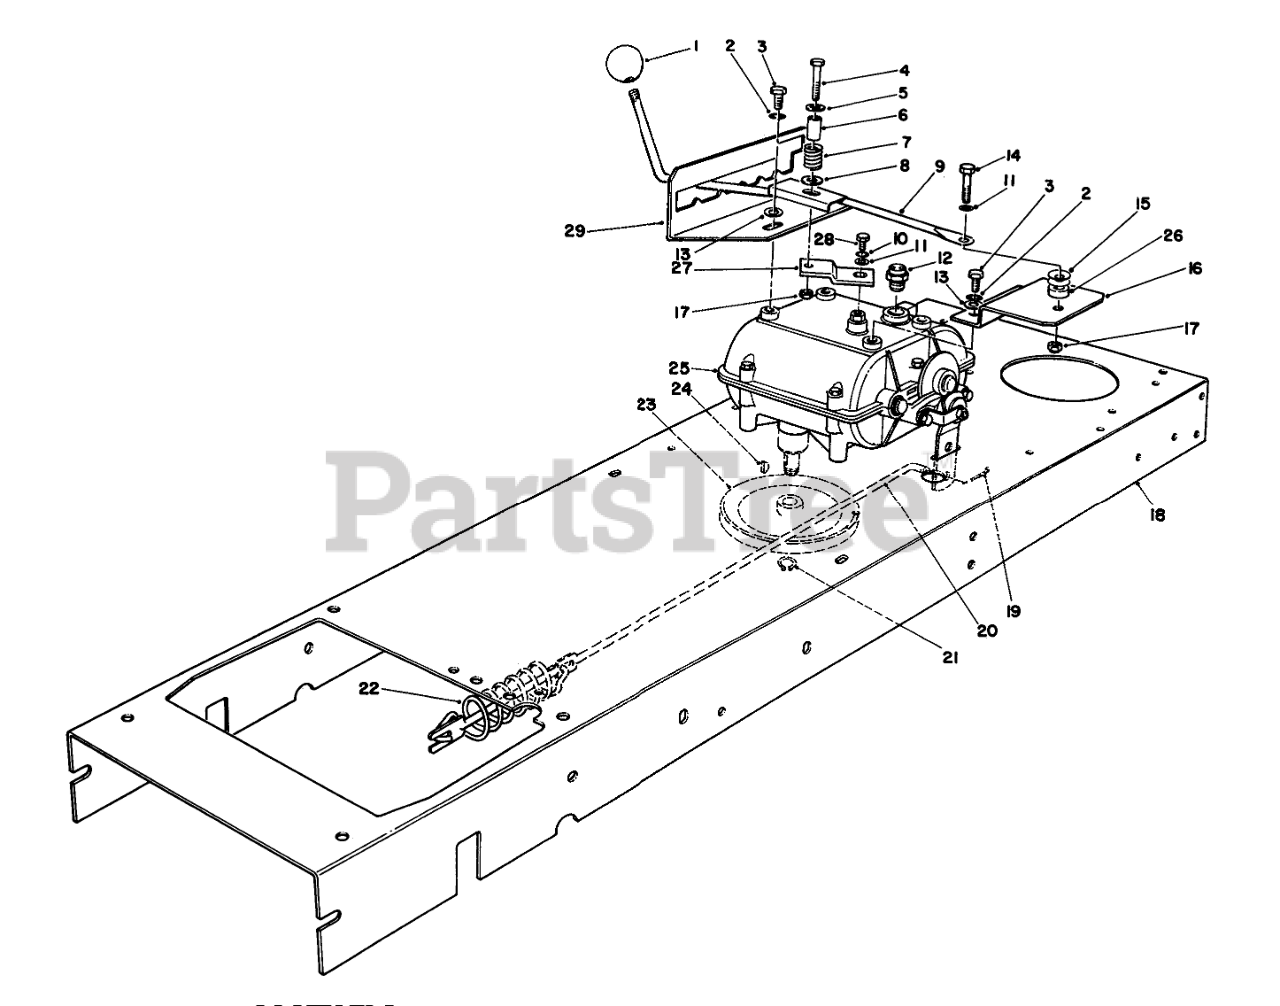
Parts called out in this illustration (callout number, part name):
2	WASHER-LOCK
3	SCREW-HWHTF
4	SCREW-HH
5	WASHER-FLAT
6	SPACER-SPLIT
7	SPRING-COMPRESSION
8	WASHER-FLAT
9	Lever-Shift
10	WASHER-LOCK
11	WASHER-FLAT
12	NEUTRAL SWITCH
13	WASHER-PLAIN
14	SCREW-HH
15	PUSH IN NUT
16	BRKT - SHIFTER MTG B
17	NUT-LOCK, NI
18	Frame-Main
19	Pin-Cotter
20	BRAKE ROD
21	RING-SNAP, EXTERNAL
22	SPRING-EXT
23	PULLEY
24	KEY-WOODRUFF
25	TRANSMISSION
26	SPACER-PIVOT
27	LEVER-SHIFT
28	Screw-Cap Hex. Hd.
29	Gate-Shift
